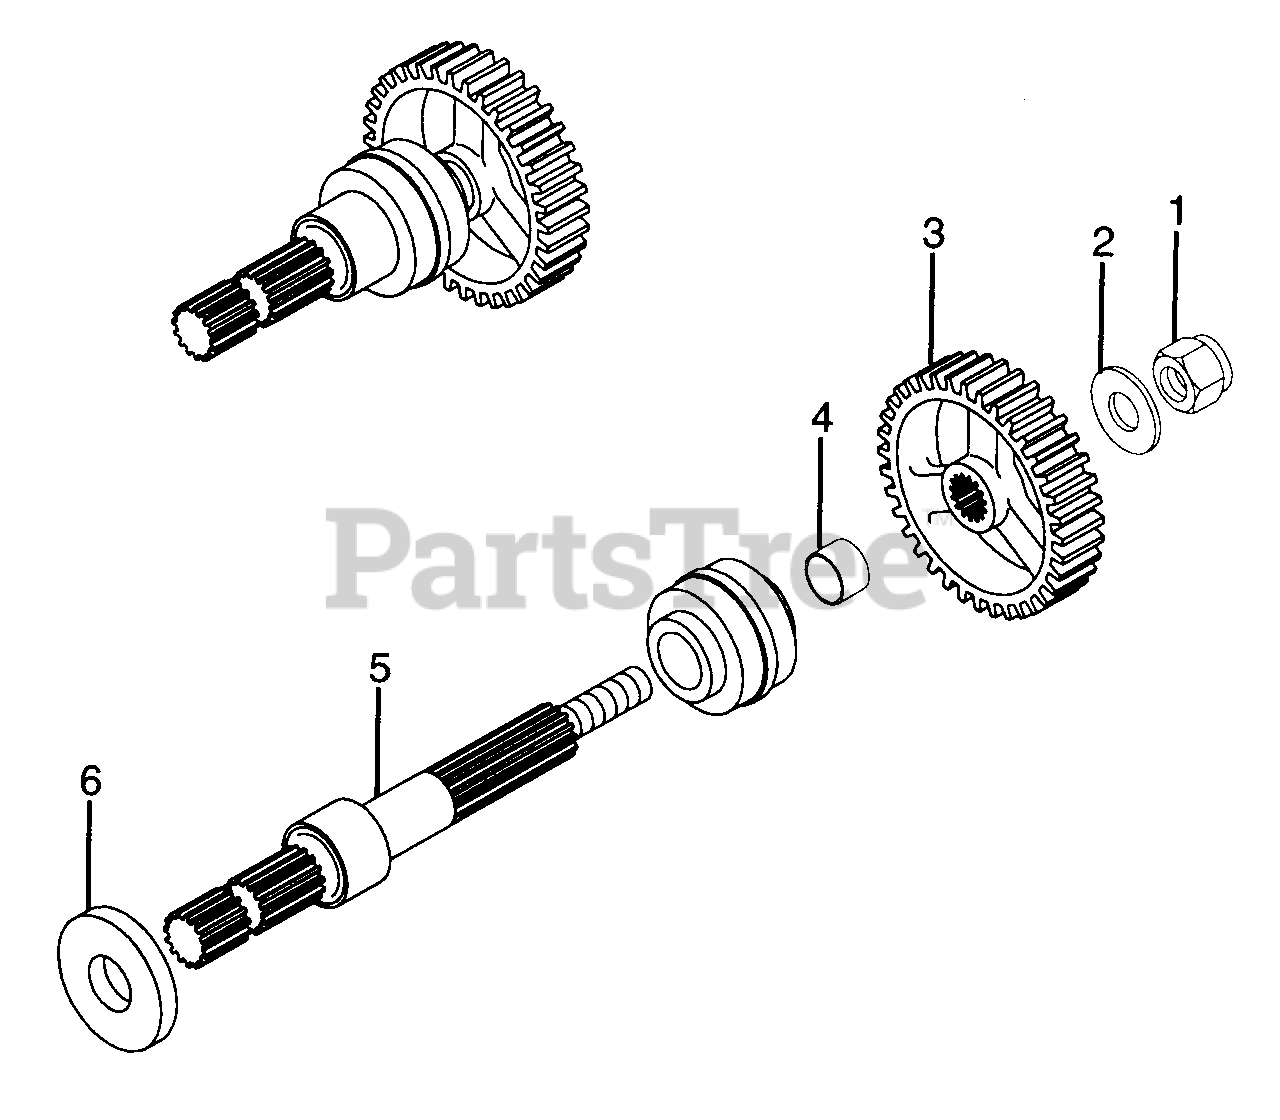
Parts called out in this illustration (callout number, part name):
1	Nut-Locking-Nylon .250-20 Grade 2
2	Washer-Flat-Steel .656 x 1.312 x .095
3	Gear-Spur PTO 10 DP 56 T
4	Bushing-Sleeve 1.06 x 1.38 x 1.38
5	Shaft-PTO
6	Seal 1.375 x 2.129 x 3.15
